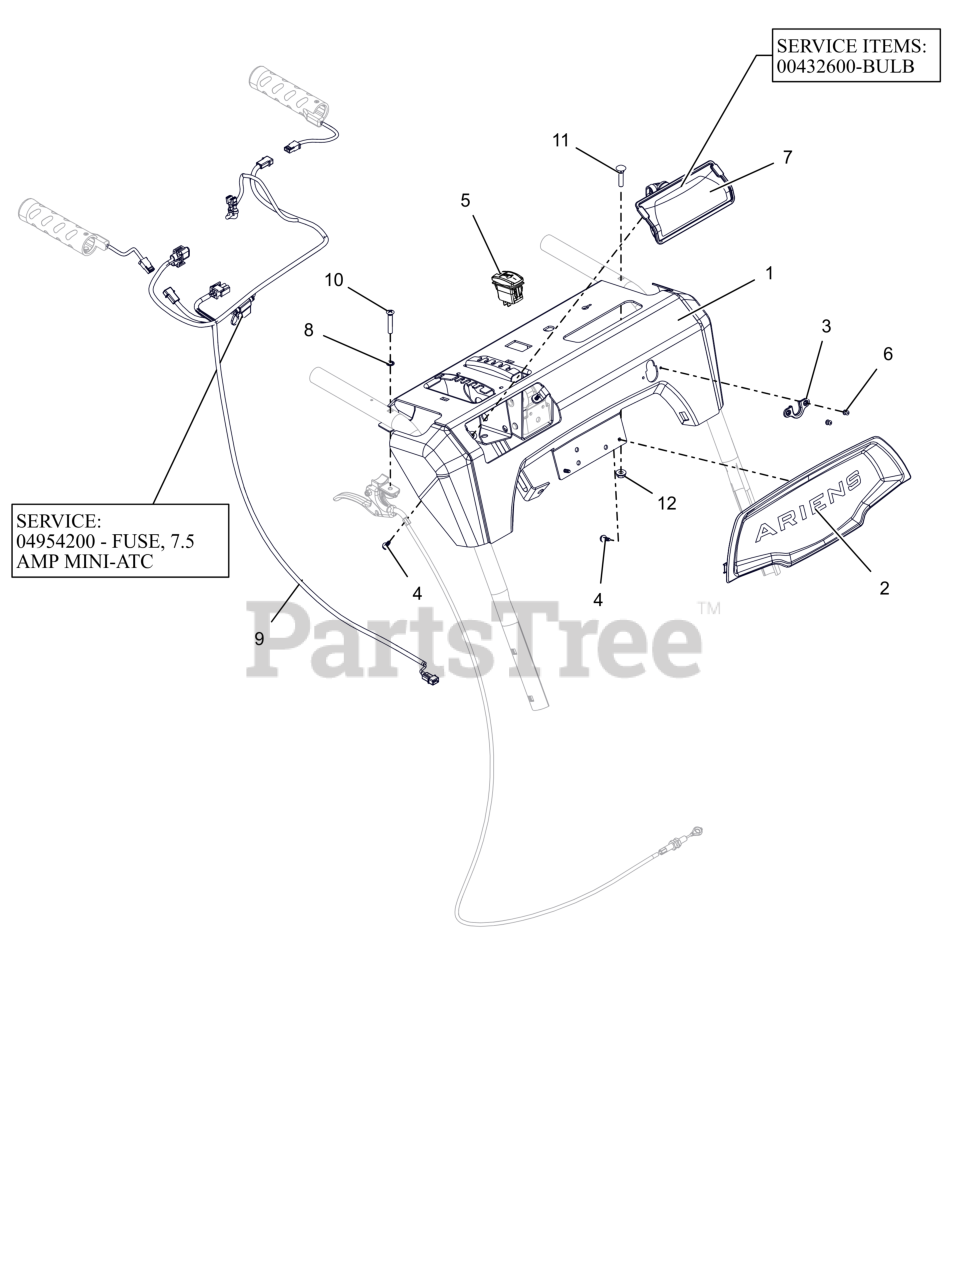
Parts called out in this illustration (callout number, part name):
1	PANEL, CONTROL-EFI QT TK W/DECALS
2	BEZEL, DASH - ARIENS LG DASH
3	GROMMET, CABLE, QUICK TURN 2
4	SCR, PLASTIC #10X.50
5	SWITCH,ROCKER SPST-ON/OFF
6	RVT-POP #43 .125X.313 STL ZINC
7	HEADLIGHT ASY, HALO 20W 2SHOT
7	BULB, LIGHT-HALOGEN 20W
8	WSHR-LK-INT .250 TH TYA
9	HARNESS,LIGHT&WARMER - EFI
10	SCR,OVAL .25-20X1.50 ZCC
11	BLT-RDHDXLSQNK.25-20X1.25 G5ZC
12	NUT-LK-CTR-FLG .25-20 ZC120
